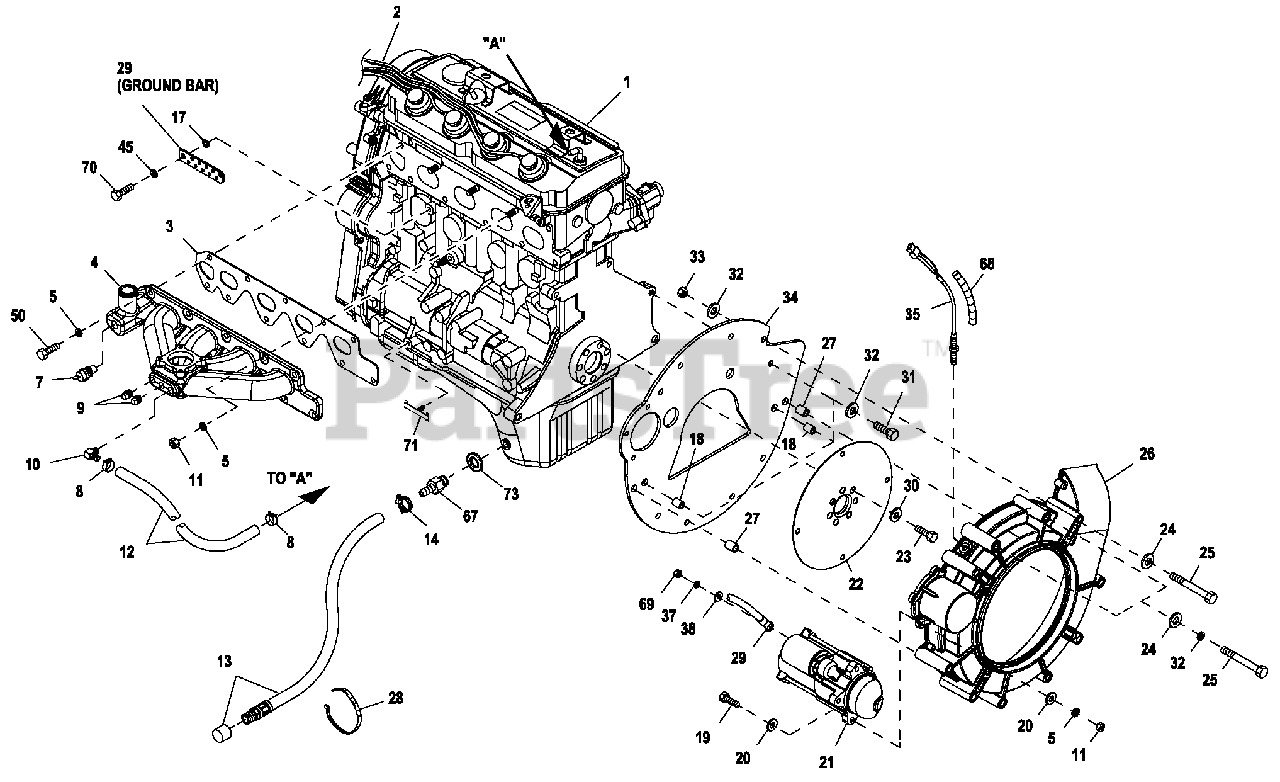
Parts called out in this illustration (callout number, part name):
1	ENGINE 2.4L G2
2	SPARK PLUG WIRE SET 2.4L G2 IG
3	GASKET INTAKE MANIFOLD G2
4	MANIFOLD INTAKE (MA CHINED)
5	WASHER LO CK M8-5/16
7	SWITCH HI-TEMP 245D X 3/8 NPT
8	CLAMP HOSE BAND .63
9	PLUG STD PIPE 1/4 STEEL SQ HD
10	BARBED EL 90 1/4 NPT X 3/8
11	NUT HEX M8-1.25 G8 CLEAR ZINC
12	HOSE 3/8 ID SINGLE BRAID (15" LG)
13	HOSE OIL DRAIN ASSY 21"
14	CLAMP HOSE .38-.87
17	WASHER SHAKEPROOF EXT 7/16 STL
18	BUSHING GUIDE 11.3MM LONG
19	S CREW HHC M8-1.25 X 45 C8.8
20	WASHER FLAT 5/16-M8 ZINC
21	MOTOR STARTER
22	PLATE FLEX 2.4L 10" ALT
23	S CREW HHC M12-1.25 X 15 C10.9
24	WASHER FLAT 3/8-M10 ZINC
25	S CREW HHC M10-1.25 X 100 PC8.8
26	HOUSING BLOWER MA CHINED 2.4L
27	BUSHING GUIDE 19.3MM LONG
28	TIE WRAP U L 7.4"X .19" B LK
30	WASHER FLAT .531 ID X 1.062 OD
31	S CREW HHC M10-1.25 X 45 C 8.8
32	WASHER LO CKM10 RIBBED ZINC
33	NUT HEX M10-1.25 G8 YEL CHR
34	ADAPTER ENGINE PLATE 2.4L G2
35	ASSY MAGPICKUP (3/8-24 MALE)
37	WASHER LO CKM6-1/4
38	WASHER FLAT 1/4-M6 ZINC
45	WASHER LO CKM10
50	S CREW HHC M8-1.25 X 25 C10.9
67	ADAPTER DRAIN OIL
68	CO N DUIT FLEX .25"ID (6"LG)
69	N UT HEX M6 X 1.0 G8 YEL CHR
70	SCREW HHC M10-1.25 X 20 C8.8
71	A N CHOR HAR N ESS
72	SPACER DC ALTER NATOR PULLEY
73	WASHER NYLO N .565
